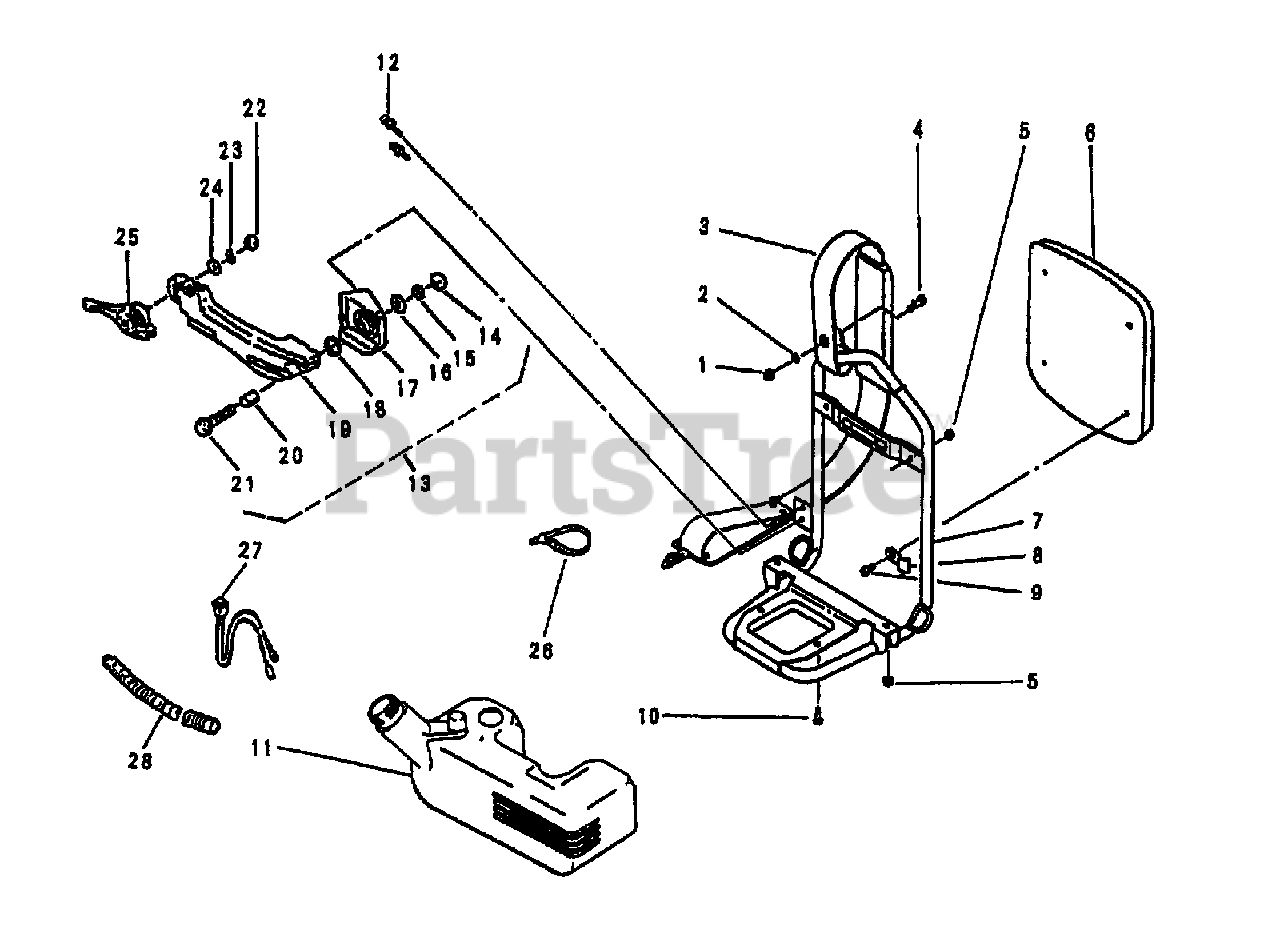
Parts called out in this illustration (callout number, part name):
1	Flange Nylon Nut (M6)
2	Washer
3	Shoulder Band
4	Truss Screw (M6x20)
5	Flange Nut
6	Backpack Pad
7	Backpack Frame
8	Backpack Pad Fitting
9	Hex Bolt (M5x12)
10	Screw (M6x10)
12	Screw (M5x12)
13	Lever Assy.
15	Spring Lock Washer (M8)
16	Toothed Lock Washer (M8)
21	Flange Bolt (M8x25)
22	Hex Nut (M5)
23	Spring Lock Washer (M5)
24	Plain Washer (M5)
25	Throttle Lever
26	Wire Band
27	Stop Switch
